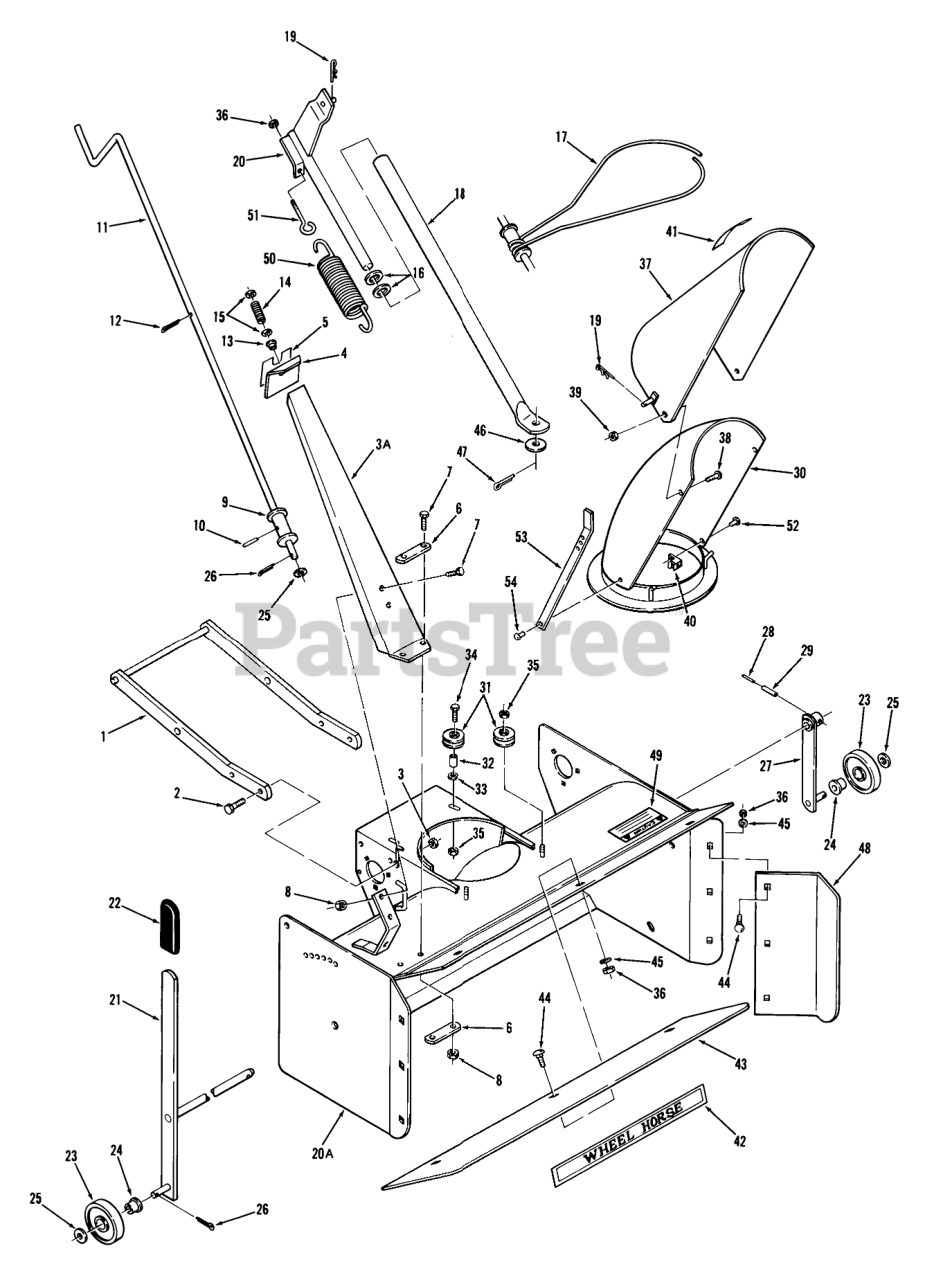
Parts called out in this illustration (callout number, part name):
1	Frame-Mounting
2	Bolt
3	Nut
3A	Crank Support
4	Decal Plate
5	Decal-Snow Guide
6	Bar-Reinforcing
7	Bolt
8	Nut
9	ASSY TUBE CRANK R
10	ROLL PIN 1/4 X 1-1/4
11	Crank
12	Pop Rivet
13	NYLINER BUSHING
14	SPRING-COMPRESSION
15	Washer
16	Washer
17	CABLE
18	Lift Tube
19	Hairpin
20	LIFT ROD ASM
20A	Wrapper Assembly
21	ASSY AUGER SHAFT R
22	GRIP
23	WHEEL BUSHING ASSY R
24	Bushing
25	Washer
26	Pop Rivet
27	Wheel Support
28	ROLL PIN 1/4 X 1-1/4
29	PIN-SPIROL
30	S/A SHROUD R
31	Roller
32	SPACER
34	Bolt
35	Nut
36	NUT
37	Deflector
38	MACH. SCREW
39	Nut
40	CLAMP
41	Decal-Caution
42	DECAL-WHEEL HORSE
43	Plate
44	Bolt
45	Washer
46	WASHER
47	Cotter Pin
48	Plate
49	Decal-Safety
50	SPRING
51	EYEBOLT
52	RIVET-4
53	ARM R
54	RIVET
